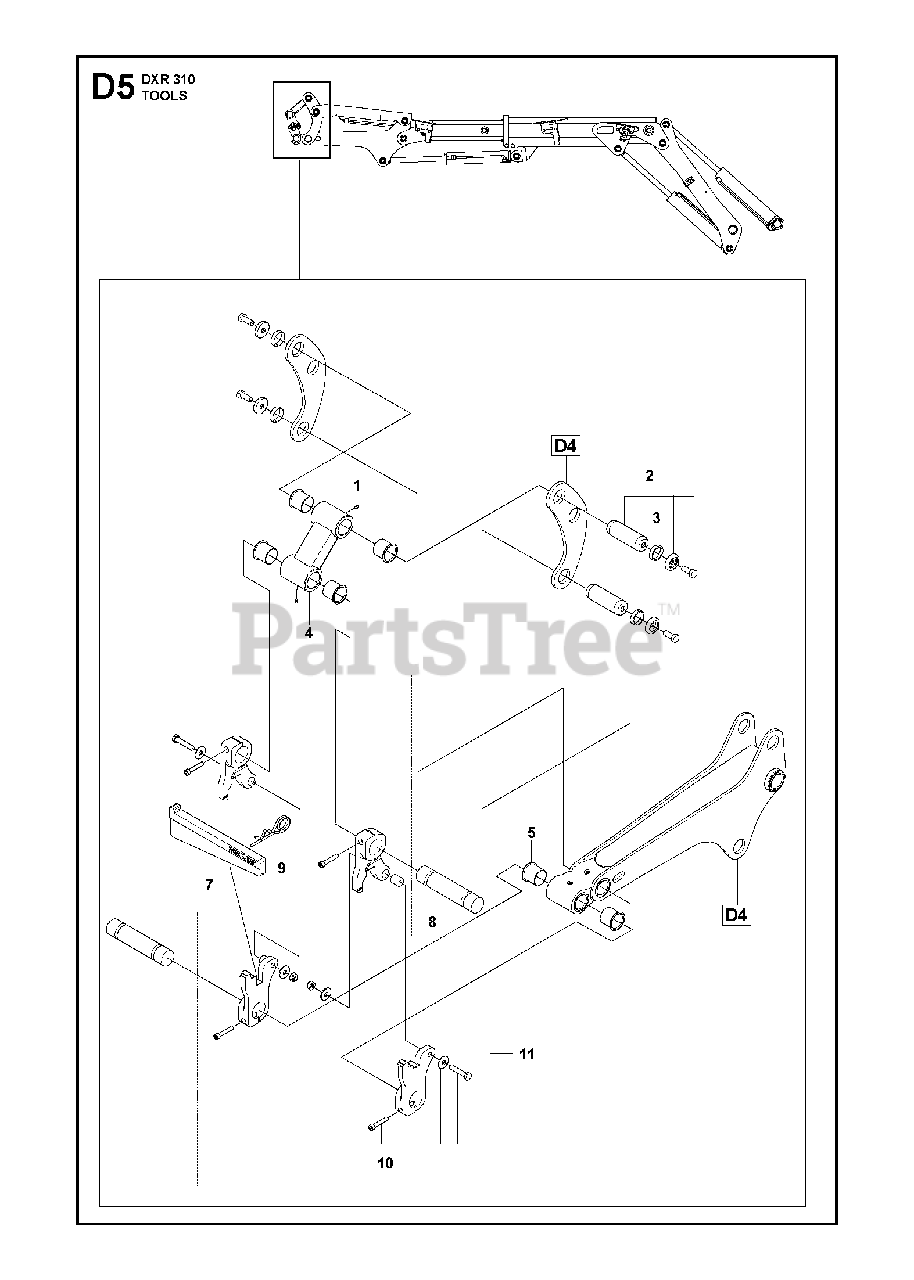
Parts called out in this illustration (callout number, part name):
7	WEDGEvalid for old tool hitch
8	SHAFTvalid for old tool hitch
9	CLIPvalid for old tool hitch
10	KITvalid for old tool hitch
11	HITCHvalid for old tool hitch
